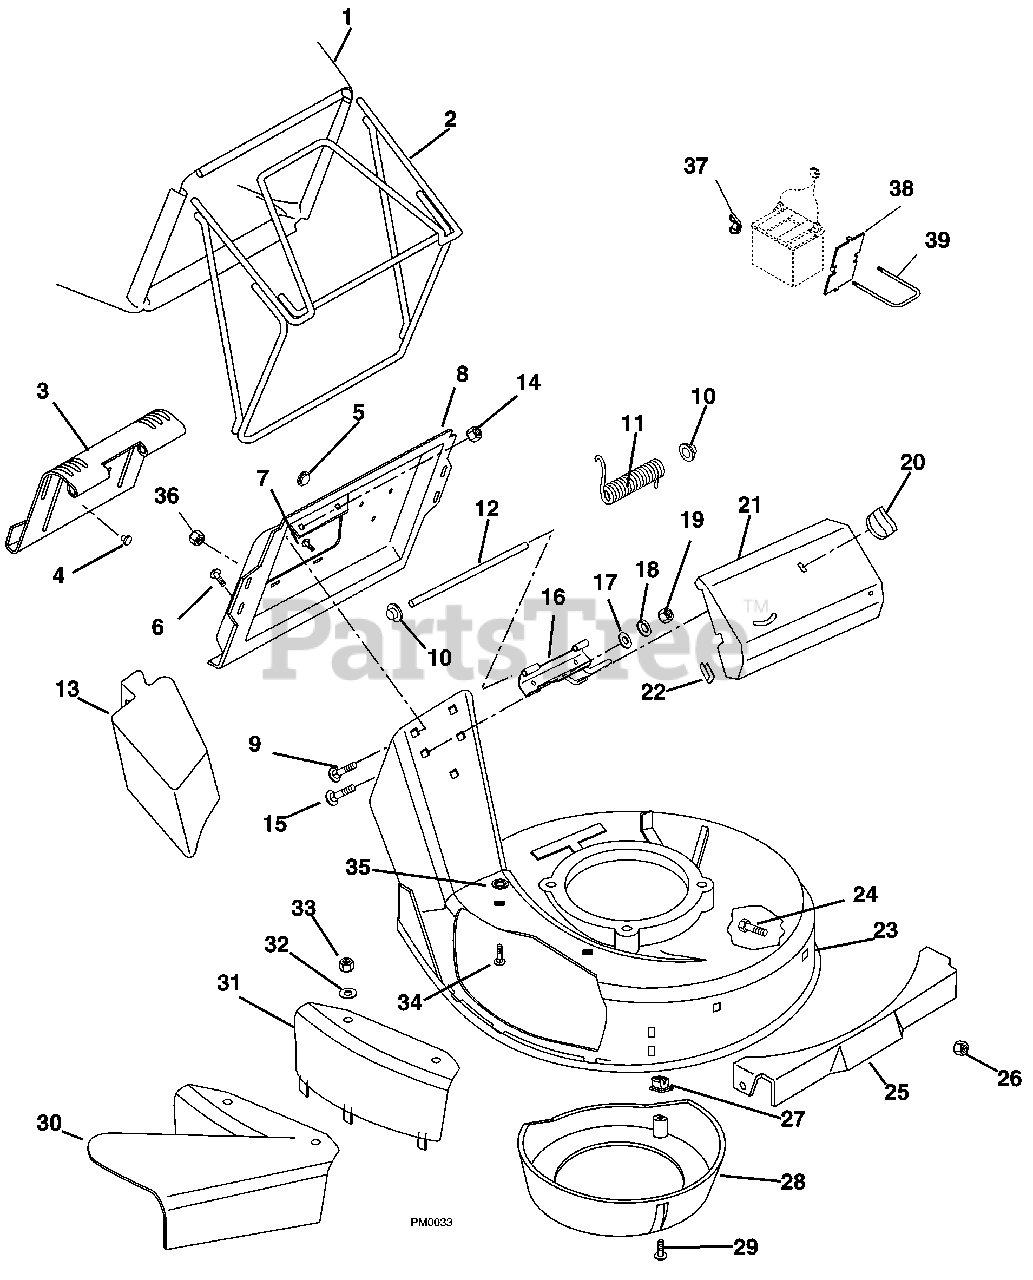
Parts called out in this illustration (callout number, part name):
1	Bag-ConsumerSilver
2	Bagger Frame
3	Door-Catcher Plate
4	Button Bumper
6	Screw-Tapping 12-24 x .50 Hex Washer
7	Screw-Tapping 10-24 x .38 Pan Head
8	Plate-Catcher
9	Bolt-Round Head Square Neck .25-20 x .38
11	Spring-Torsion .120 x .68 x 3.09
13	Mulch Master Mulcher Accessory
14	Nut-Locking-Flange .25-20
15	Bolt-Round Head Square Neck .25-20 x .75 Grade 5
16	Hinge Base Weldment (580 RS, 580 RSW, 580 BBC,600 C)
17	Washer-Flat-Steel .328 x .87 x .179
18	Washer-Locking .25 x .077
19	Nut-Hex .25-20
20	Nut-Wing (580 RS, 580 RSW, 580 BBC, 600 C)
21	Drive Cover (580 RS, 580 RSW, 580 BBC, 600 C)
22	Trim Bumper
23	Mower Pan Head with Decals (580 RS, 580 RSW, 580 BBC, 600 C)
24	Bolt-Round Head Square Neck .31-18 x .50 Grade 5 (580 RS, 580 RSE, 580 RSW)
25	Front Panel
26	Nut-Locking-Center .31-18 (580 RS, 580 RSE, 580 RSW, 600 C)
27	Grommet-Plastic
28	Baffle-Center
29	Screw-Tapping 10-16 x .62 Hex Washer Head
30	Side Discharge Assembly
31	Side Discharge Cover
32	Washer-Flat-Steel .406 x .812 x .065
33	Nut-Locking-Nylon .312-18
34	Bolt-Round Head Square Neck .31-18 x .75 Grade 2
35	Nut-Push .312
36	Nut-Locking-Flange .250-20 (600 C)
37	Nut-Wing #8-32
38	Battery Plate (580 RSE)
39	U-Bolt (580 RSE)
